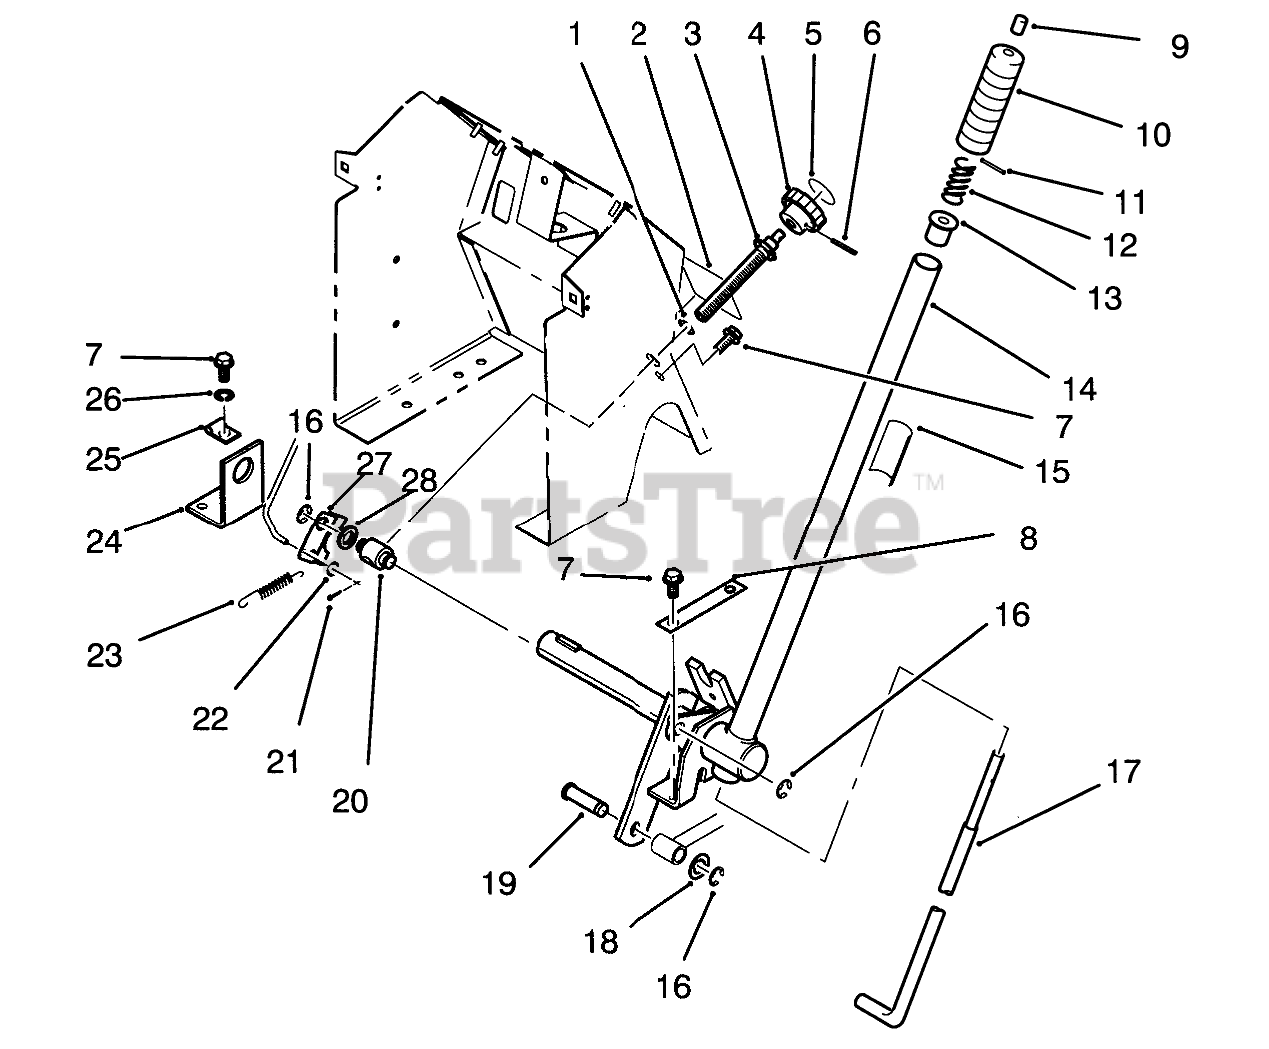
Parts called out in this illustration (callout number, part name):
1	Washer
2	DECAL-MWR ADJUST
3	ROD B
5	DECAL-HEIGHT KNOB
6	PIN-SPIROL
7	Screw
8	Plate
9	CAP-ROD, PLUNGER
10	HANDGRIP
11	PIN-SPIROL
12	SPRING-COMPRESSION
13	RETAINER-SPRING
14	WLDMT-LIFT HANDLE B
15	DECAL-LIFT
16	RING-RETAINING, EXTERNAL
17	ROD-LATCH LIFT
18	WASHER-FLAT
19	ASS'Y-WHEEL & TIRE
20	TRUNNION
21	Cotter Pin
22	WASHER-FLAT
23	SPRING-EXTENSION
24	BRACKET B
25	THROTTLE CONTROL CLP
26	Washer-Lock
27	PLATE B
28	Washer
